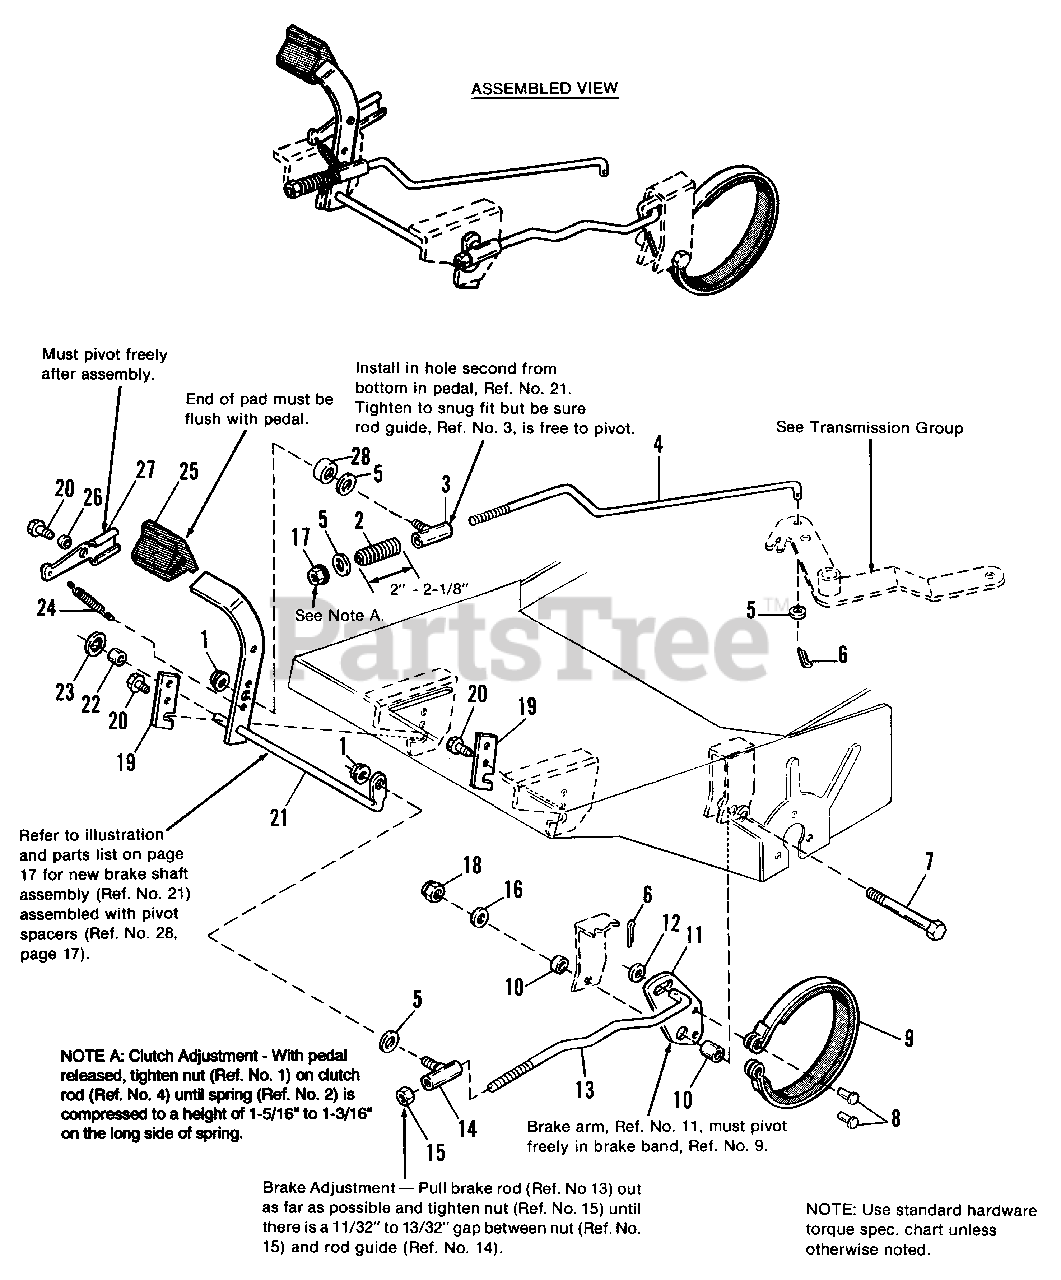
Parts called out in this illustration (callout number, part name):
1	NUT, Hex Lock, 5/16-18
3	GUIDE ASSY., Rod (Clutch)
4	ROD, Clutch
5	WASHER, 11/32 x 3/4
6	PIN, Cotter, 3/4
7	CAPSCREW, Hex, 1/2-13 x 3-1/2, Gr. 5
9	BAND ASSY., Brake
11	LINK, Brake Arm
12	WASHER, 3/8
14	GUIDE ASSY., Rod (Brake)
15	NUT, Hex, Lock, 3/8-16
16	WASHER, 1/2
17	NUT, Hex, Esna Lock, 5/16-18
18	NUT, Hex, Esna Lock, 1/2-13
19	BRACKET, Brake
20	SCREW, Taptite, 5/16-18 x 1/2
21	SHAFT ASSY., Brake
25	PAD, Pedal
27	LATCH, Brake
